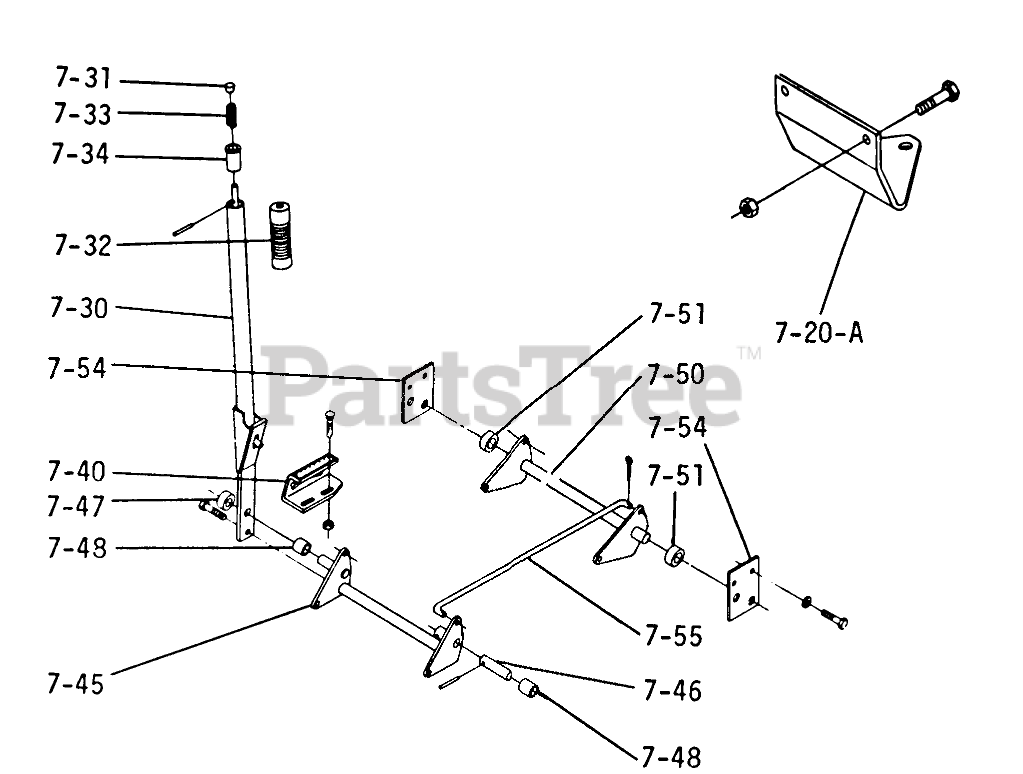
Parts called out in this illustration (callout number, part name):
7-20-A	Hitch
7-30	Assy.-Lift Lever
7-31	Cap
7-32	HANDGRIP
7-33	SPRING-COMPRESSION
7-34	RETAINER-SPRING
7-40	Quadrant-Lift
7-45	Front Lift Rod
7-47	Spacer
7-48	Bushing
7-49	Retainer
7-50	Rear Lift Rod
7-51	SPACER
7-54	Assy.-Bracket-Lift
7-55	Rod-Lift L.H.
